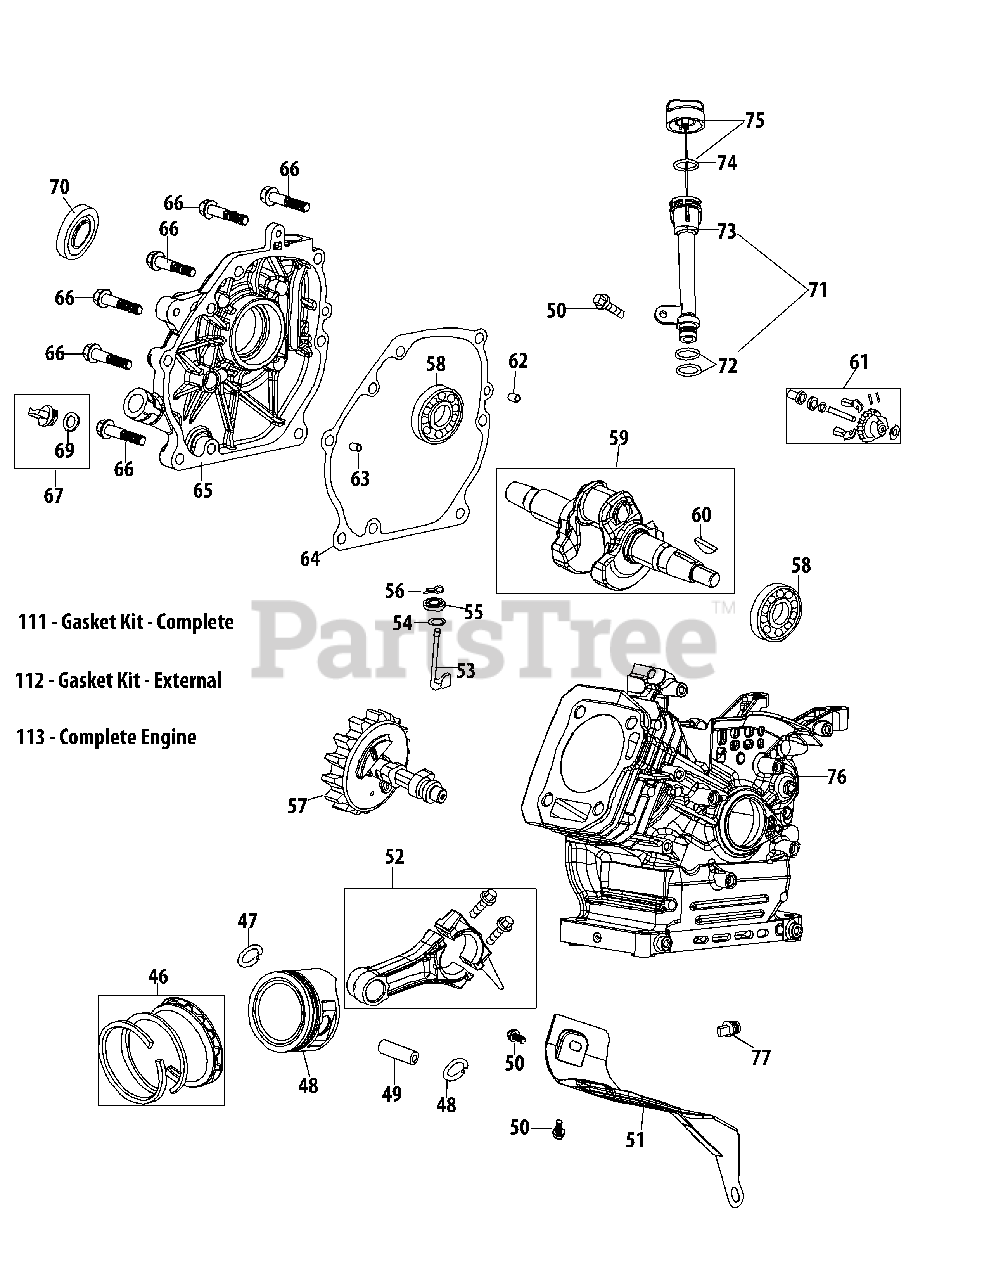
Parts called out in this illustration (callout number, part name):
46	Piston Ring Set
47	Piston Pin Snap Ring
49	Piston Pin
50	Bolt M6×12
51	Air Shield
52	Connecting Rod Assembly
53	Governor Arm Shaft
54	Washer 5.2×1.9
55	Governor Seal
56	Cotter Pin
57	Camshaft Assembly
58	Radial Ball Bearing, 6205
59	Crankshaft Kit
60	Woodruff Key
61	Governor Gear/Shaft Assembly
62	Dowel Pin 7×14
63	Dowel Pin 9×14
64	Crankcase Cover Gasket
65	Crankcase Cover
65	Crankcase Cover Kit
66	Bolt M8×32
67	Oil Fill Plug Assembly
69	O-Ring 15.8×2.5
70	Oil Seal 25×41.25×6
71	Oil Fill Tube Assembly
72	Oil Fill Tube O-Ring
73	Oil Fill Tube
74	Oil Fill Tube O-Ring
75	Dipstick Assembly
76	Crankcase
76	Crankcase Kit
76	Short Block Assembly
77	Oil Drain Plug
111	Gasket Kit - Complete
112	Gasket Kit - External
113	Complete Engine
